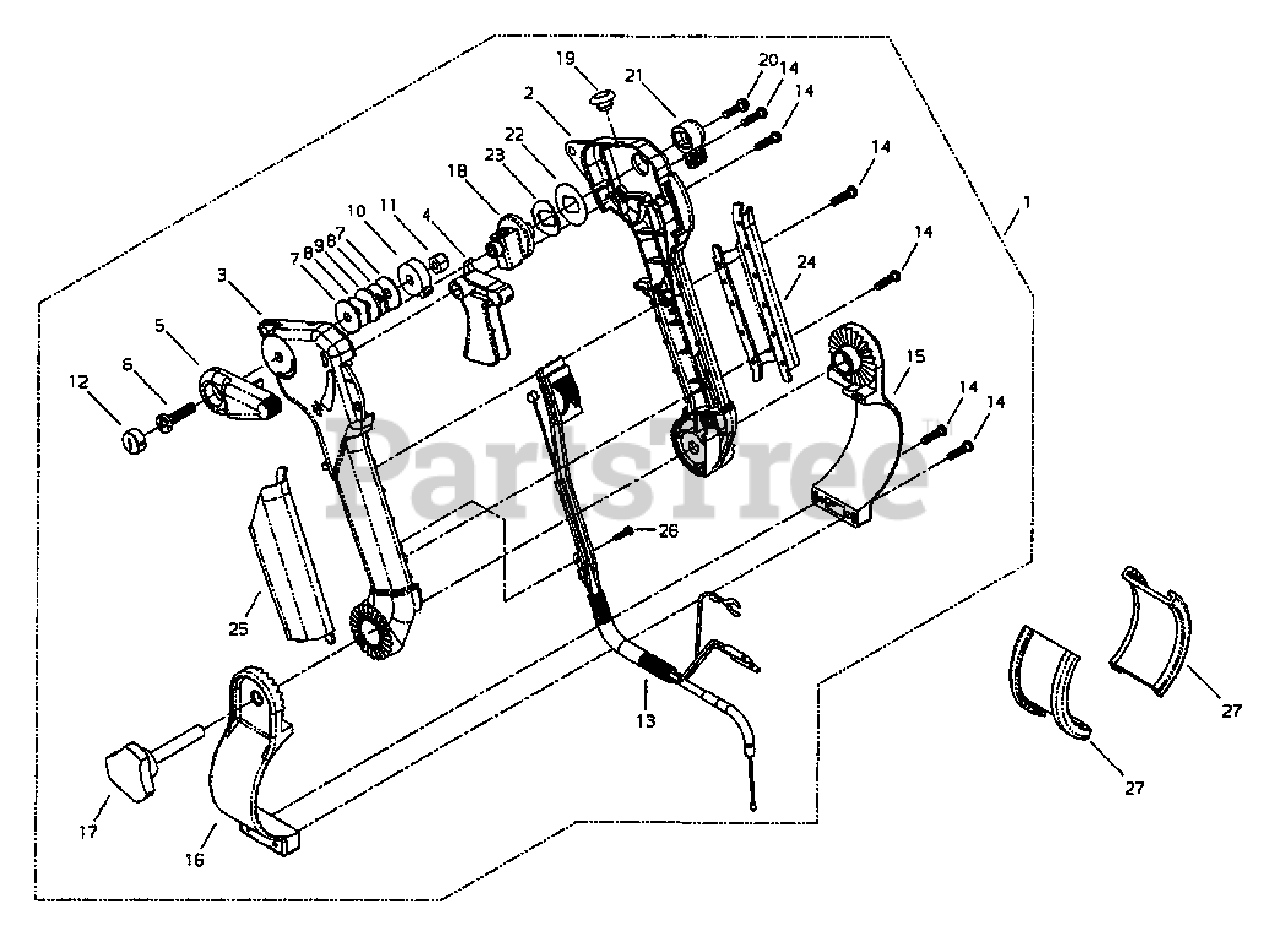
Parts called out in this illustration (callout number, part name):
1	THROTTLE LEVER ASSY
2	STAY
4	TRIGGER, THROTTLE
5	LEVER, LOCK
6	ADJUSTABLE BOLT
7	WASHER - 6
8	LOCKWASHER
9	WASHER - 6
10	PLATE
11	NUT - 6 -- NYLON
12	CRUISE CONTROL BOLT CAP
13	THROTTLE CONTROL ASSY
14	SCREW
15	BRACKET, HANDLE - RIGHT
16	BRACKET, HANDLE - LEFT
17	KNOB, FASTENER
18	ADJUSTER ASSY
19	PLUG
20	SCREW, METERING LEVER PIN
21	SCREW, METERING LEVER PIN
22	WASHER
23	WASHER - SPRING
24	GRIP - RIGHT
25	GRIP, HANDLE - LEFT
26	SCREW
27	SPACER
